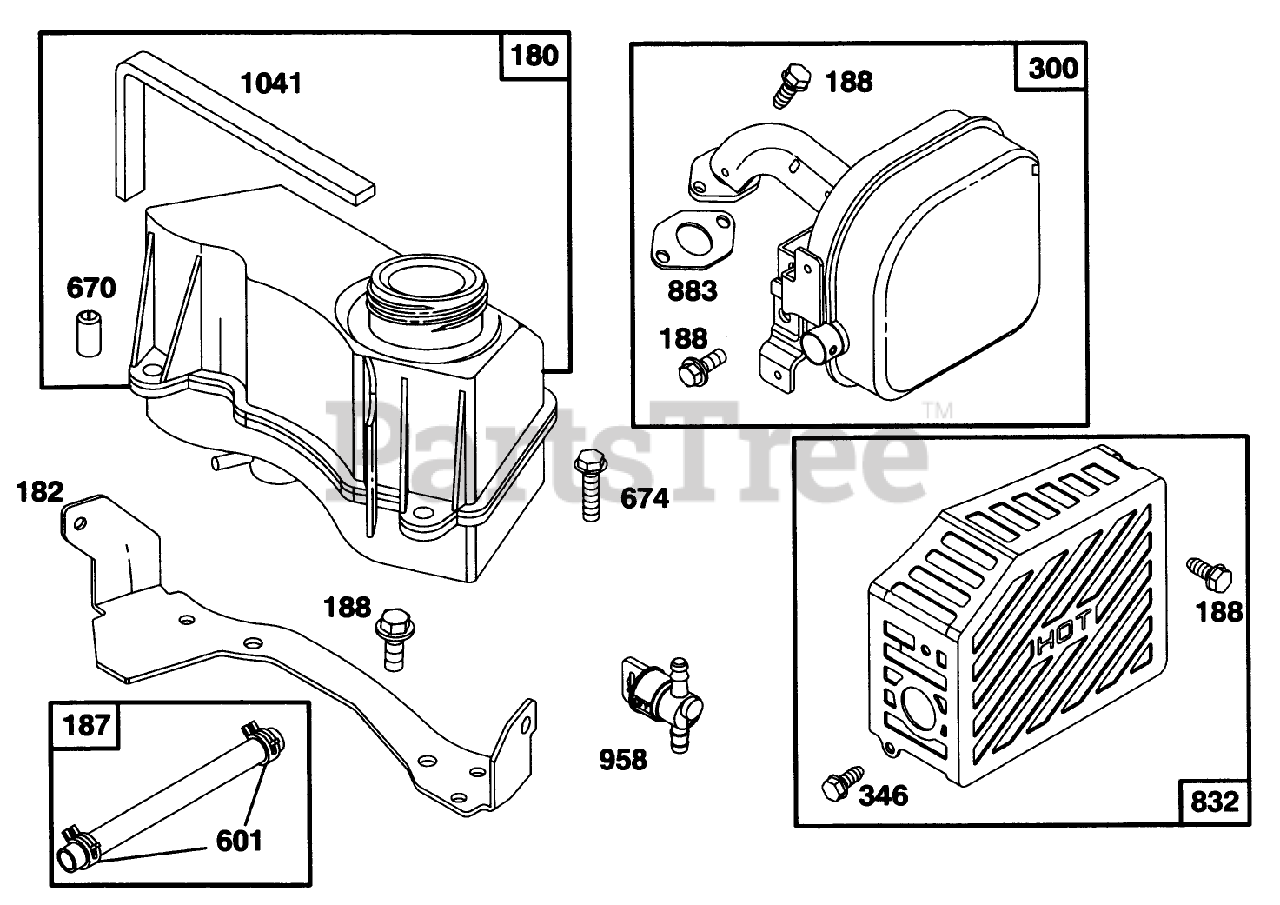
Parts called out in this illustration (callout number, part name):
180	TANK ASSY - FUEL
187	BRIGGS 296004
188	SCREW - HEX HEAD
300	MUFFLER - EXHAUST
670	SPACER
674	SCREW - HEX HEAD
